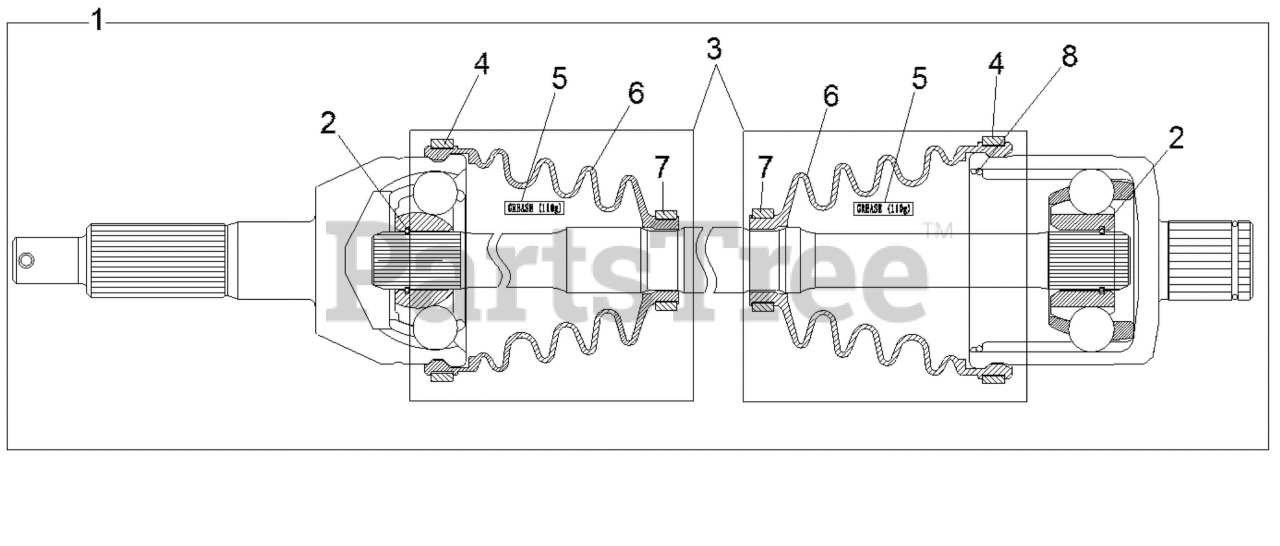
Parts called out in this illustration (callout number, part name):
1	ASM-DRIVESHAFT,REAR
2	CIRCLIP
3	KIT-BOOT(PR-8071)
4	CLAMP-LARGE(PR-0027)
5	GREASE(K575/VW738)
6	BOOT(PR-0025)
7	CLAMP-SMALL(PR-0026)
8	RING-RUBBER(JIB)
